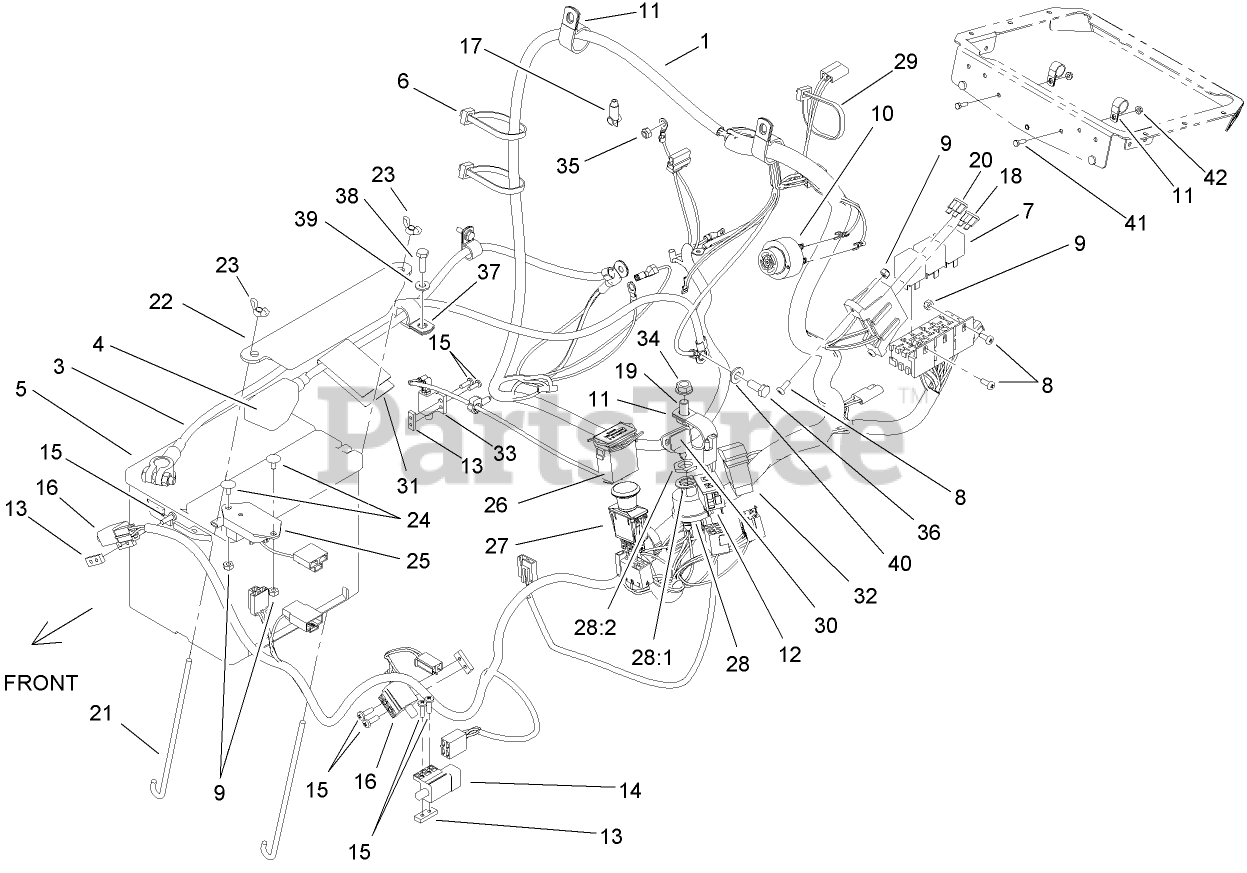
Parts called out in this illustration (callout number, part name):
1	HARNESS-ELECTRICAL, MAIN
3	CABLE-BATTERY, NEGATIVE
4	CABLE-BATTERY, POSITIVE
5	BATTERY-DRY
6	TIE-PLASTIC
9	NUT-LOCK, NI
10	ALARM-TONE, DUAL
11	CLIP-LOOM
12	LAMP-WARNING
13	PLATE-TAPPED
14	SWITCH
15	SCREW-PPH
16	SWITCH-OPEN, NORMALLY
17	CAP-INSULATOR, RED
18	FUSE-40 AMP
19	SCREW-HH
20	FUSE-BLADE, 30 AMP
21	Bolt-Holddown
22	HOLDDOWN-BATTERY
23	WINGNUT
24	BOLT-CARR
25	MODULE-DELAY, SEAT
26	METER-HOUR
27	SWITCH-PTO
28	SWITCH ASM
28:1	NUT-HH
28:2	WASHER-TOOTH, INTERNAL
29	TIE-CABLE
30	KEY-IGNITION
31	DECAL-INSTRUCTIONS, CHARGING
32	SWITCH-ROCKER
33	SWITCH-CLOSED, NORMALLY
34	NUT-HHF, WHIZ
35	NUT-LOCK
36	SCREW-HH
37	CLIP-LOOM
38	SCREW-HH
39	WASHER-FLAT
40	WASHER-PLAIN
41	SCREW-HH
42	NUT-HF
